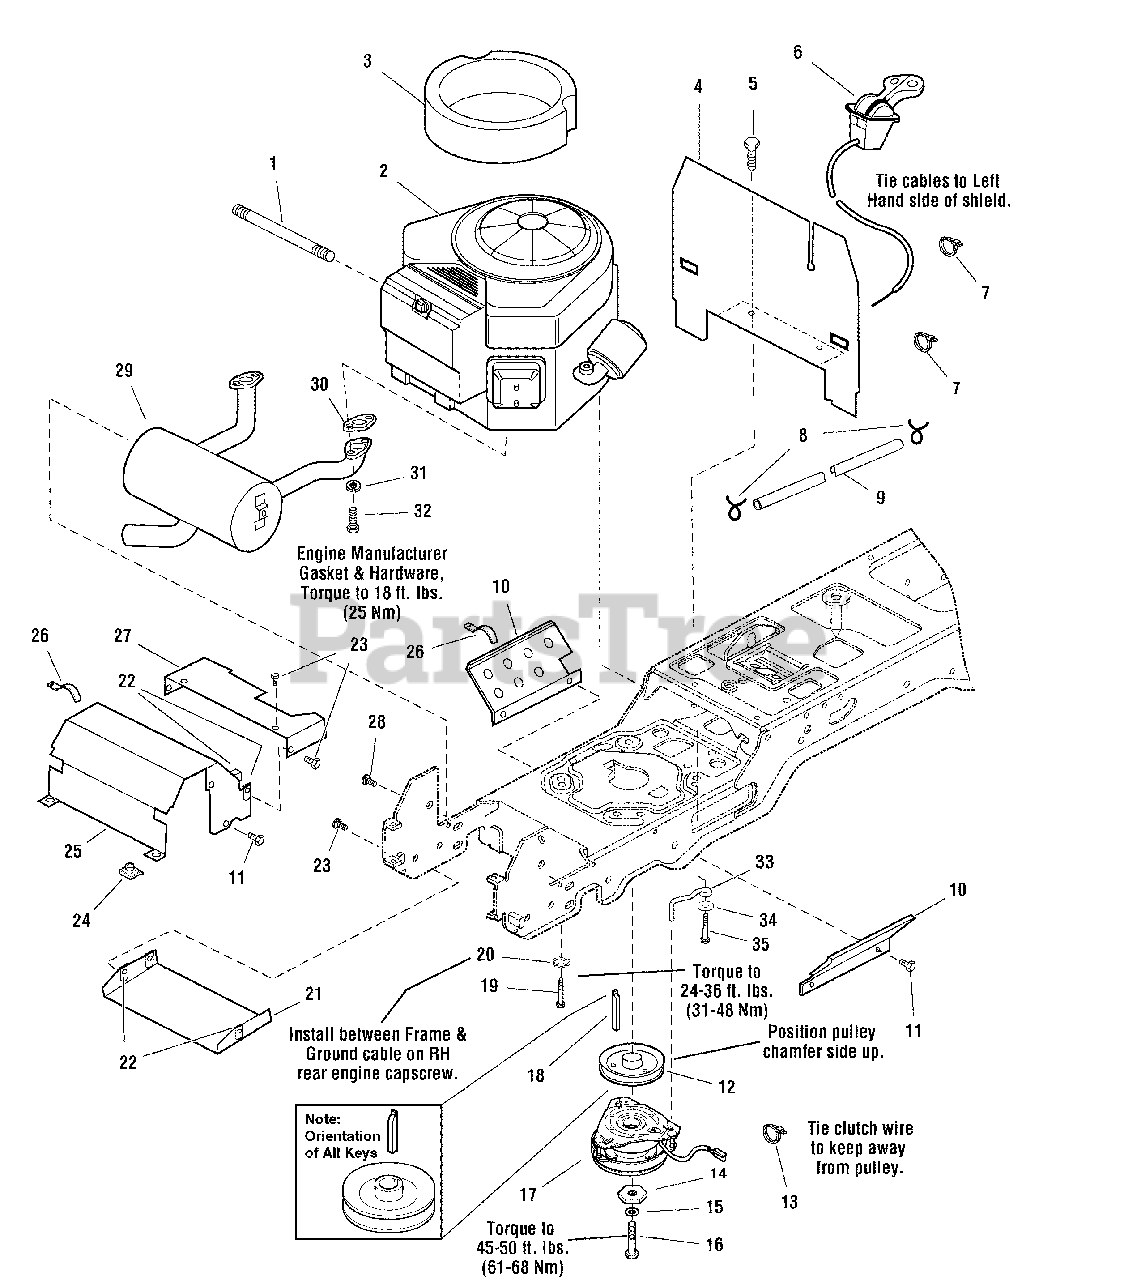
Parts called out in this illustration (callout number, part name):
1	HOSE, Oil Drain, 10-1/2" Long, 3/8-18 Fittings
3	SEAL, Circle, 16HP Only
4	BULKHEAD
5	CAPSCREW, Hex Washer Head Taptite, 1/2-20 x 1/2, Black
6	CONTROL, Throttle Double 39" Long w/Knobs
7	TIE, Wire, 7-5/16" Long
8	CLAMP, Hose Type E
9	HOSE, Fuel, 59" Long
10	SHIELD, Side
11	CAPSCREW, Hex Washer Head Taptite, 1/4-20 x 3/8
12	PULLEY & HUB ASSEMBLY
13	TIE, Self Locking, 3-5/8 Long
14	WASHER, Hex, 7/16, Black
15	LOCKWASHER, 7/16
16	CAPSCREW, Hex Head, 7/16-20 x 3-3/4
17	CLUTCH, Electric
18	KEY, HI PRO, 1/4 x 2 1/2
19	CAPSCREW, Hex Washer Head Taptite, 3/8-16 x 1-1/2
20	LOCKWASHER, External Tooth, 3/8
21	SHIELD, Muffler Bottom
22	NUT, Speed, 1/4-20, Lug
23	CAPSCREW, Hex Flange Whiz Lock, 1/4-20 x 5/8
24	NUT, Speed, 5/16-18, Lug, Black
25	DUCT, Muffler Top
26	CLIP, Wire 1/8
27	DUCT, Muffler Extension
28	CAPSCREW, Hex Washer Head Taptite, 5/16-18 x 1/2, Black
29	MUFFLER, Briggs & Stratton, Vanguard Twin
30	GASKET, Briggs & Stratton, Vanguard Twin
31	LOCKWASHER, 5/16
32	CAPSCREW, Hex Flange Whiz Lock, 5/16-18 x 7/8
33	RETAINER, Clutch
34	WASHER, Flat 3/8
35	CAPSCREW, 3/8-16 x 1
